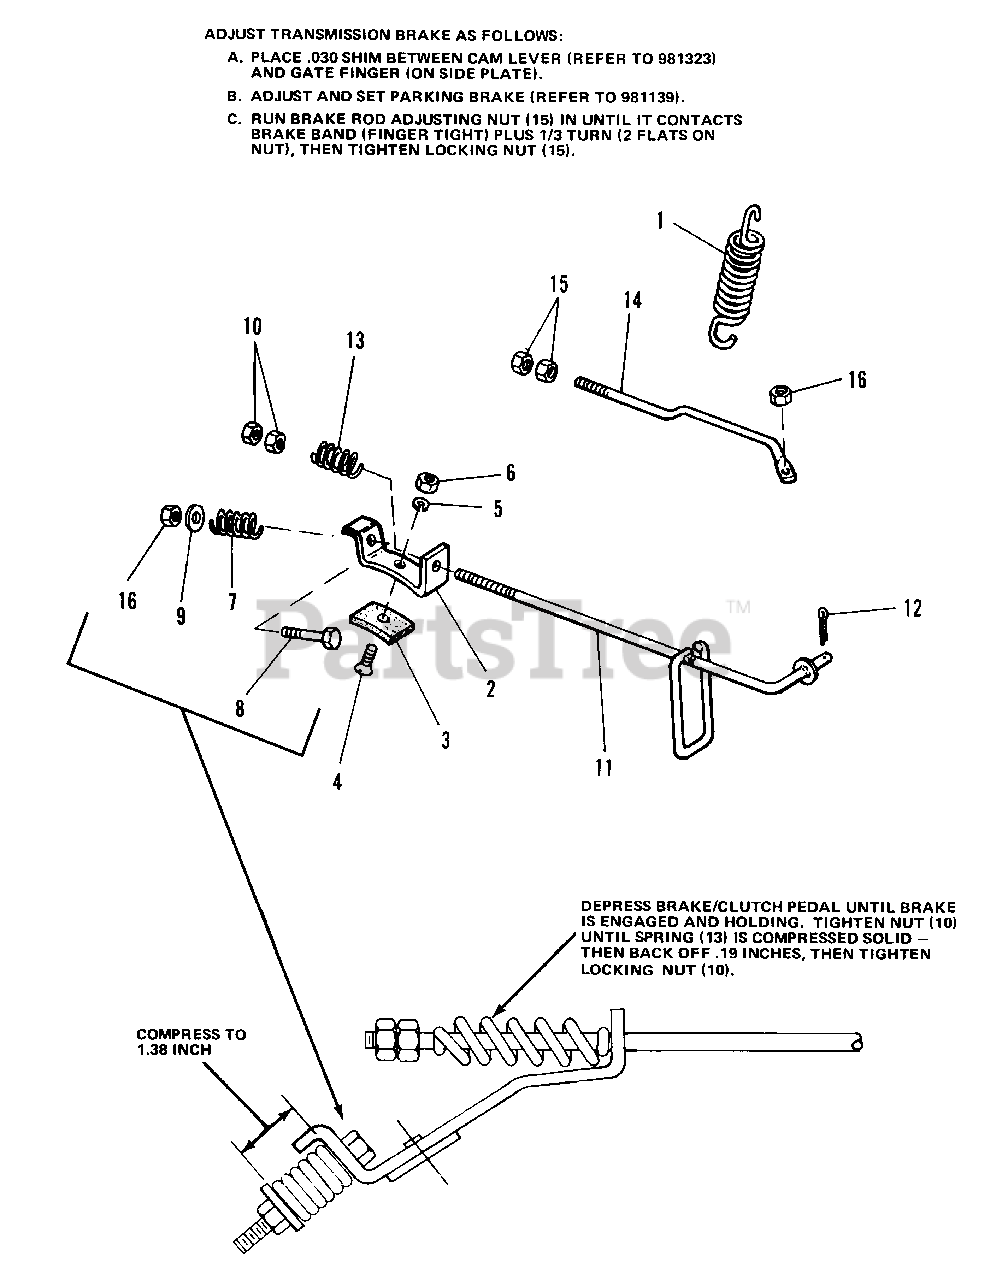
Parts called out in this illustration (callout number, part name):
2	STRAP, Pulley Brake (Mfg. No. 1690203)
2	STRAP, Pulley Brake (Mfg. No. 1690203) STRAP, Pulley Brake (Mfg. No. 1690204)
3	BRAKE, Sheave
4	SCREW, Machine, No. 10-24 x 5/8
5	LOCKWASHER, No. 10
6	NUT, Hex, Full, No. 10-24
8	CAPSCREW, 5/16-18 x 1/4
9	WASHER, 1/4 Std.
10	NUT, Hex, Full, 5/16-18
11	PULLEY BRAKE ROD ASSEMBLY
12	PIN, Cotter, 3/32 x 1/2
14	ROD, Brake
15	NUT, Hex, Full, 3/8-16
16	LOCKNUT, Hex, 5/16-18
